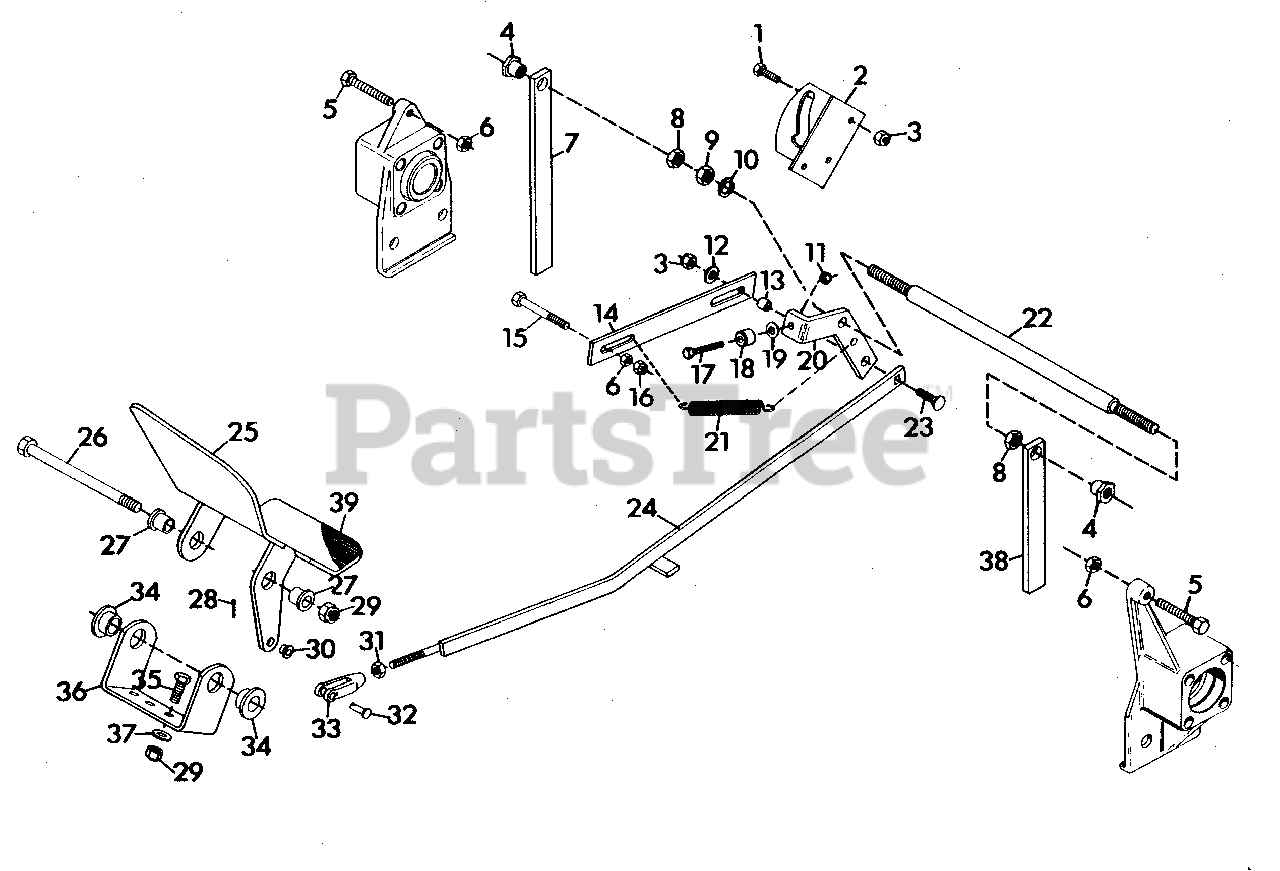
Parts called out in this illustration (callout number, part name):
1	BOLT, HEX 5/16-18X1.00
2	WELDMENT, FWD-REV ACTUATING
3	NUT, LOCK 5/16-18
4	BUSHING, FWD-REV SLIDE ROD
5	BOLT, HEX 3/8-16X2.50
6	NUT, HEX 3/8-16
7	SPRING, REVERSE CLUTCH
8	NUT, JAM 1/2-13 HEX
9	NUT, HEX 1/2-13
10	WASHER, LOCK 1/2 SP HEAVY
11	NUT, LOCK 1/4-28
12	WASHER, FLAT .313X.875X.065
13	BUSHING, FWD-REV LINKAGE
14	STRAP, NEUTRAL DETENT
15	BOLT, HEX 3/8-16X3.00
16	NUT, LOCK 3/8-16
17	BOLT, HEX 1/4-28X1.38 GR. 8
18	ROLLER, CLUTCH CAM
19	WASHER, FLAT .281X.625X.065
20	ARM, FWD-REV CLUTCH ROLL
21	SPRING, NEUTRAL DETENT
22	ROD, FWD-REV SLIDE
23	BOLT, 5/16-18X1.25 RD HD SQ NK
24	WELDMENT, FWD-REV SHIFTER
25	PEDAL, FOOT CLUTCH
26	BOLT, HEX 1/2-13X6.50
27	BUSHING, .513X.750X.625
28	PIN, COTTER .09X.75
29	NUT, LOCK 1/2-13
30	BUSHING, NYLON .32X.437X.248
31	NUT, HEX 5/16-24
32	PIN, CLEVIS 5/16X.812
33	YOKE
34	BUSHING, NYLON .76X1.00X.76 FLG
35	BOLT, HEX 1/2-13X1.25
36	BRACKET, CLUTCH PEDAL PIVOT
37	WASHER, FLAT .531X1.250X.100
38	SPRING, FWD-REV CLUTCH
39	PAD
